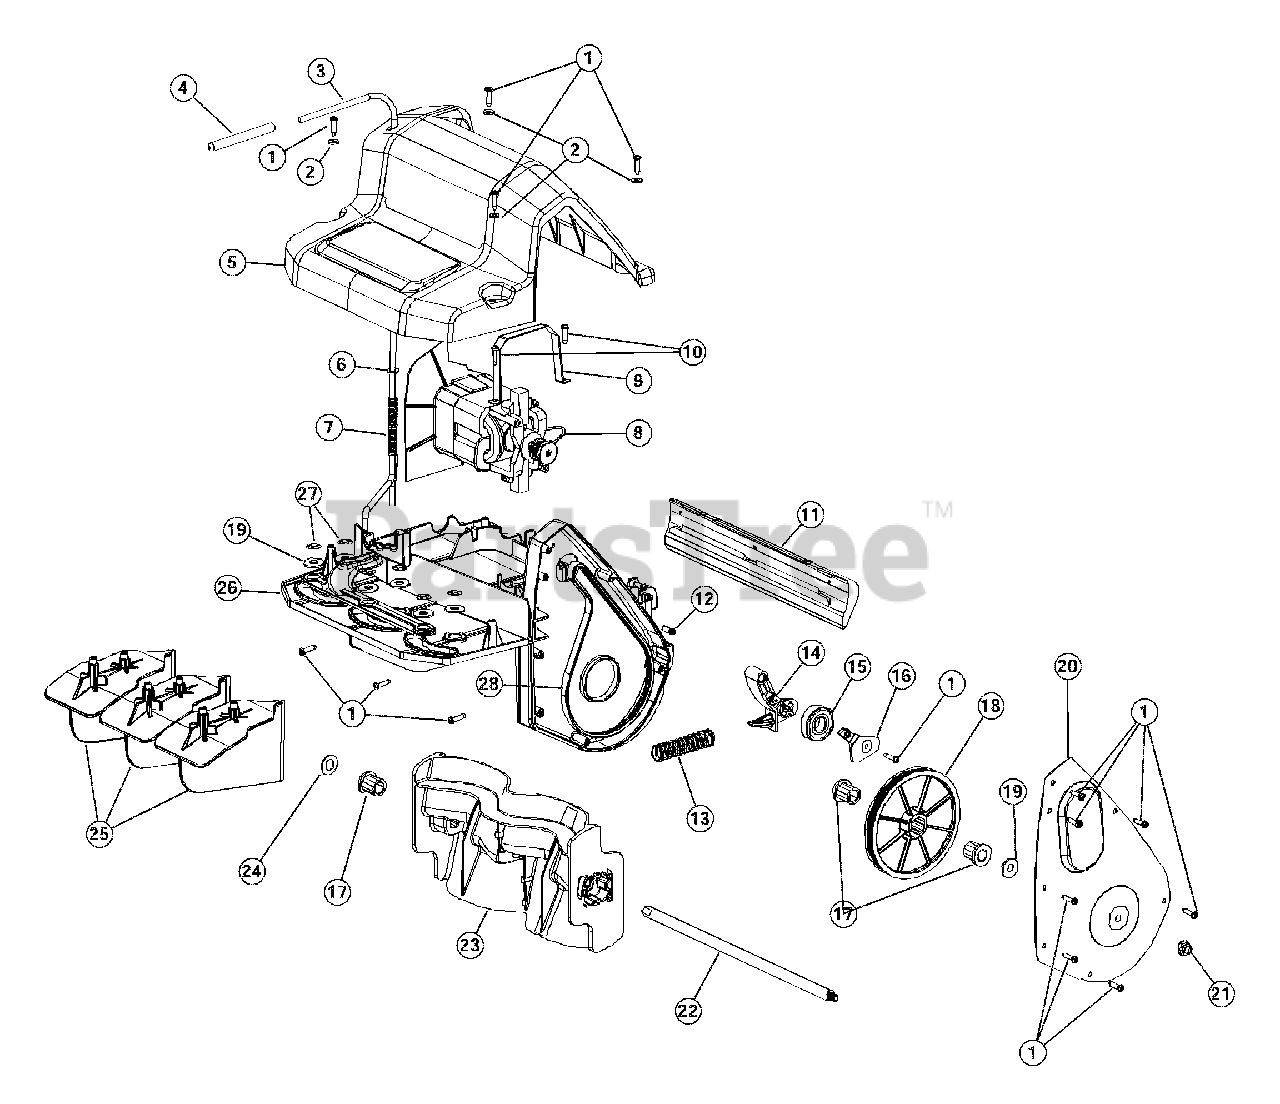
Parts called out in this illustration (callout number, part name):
3	Vane Control Handle
6	Washer
7	Spring
8	Motor Assm w/Baffle, Fan & Pulley
9	Motor Strap
10	Screw
11	Scraper
13	Spring
14	Idler Arm
15	Ball Bearing
16	Keeper
17	Flange Bearing
18	Driven Pulley
19	Washer
20	Bert Case Cover
21	Flange Lock Nut
22	Axle Auger
25	Vane
26	Snow Thrower Housing
27	Push Nut
28	Drive Belt
